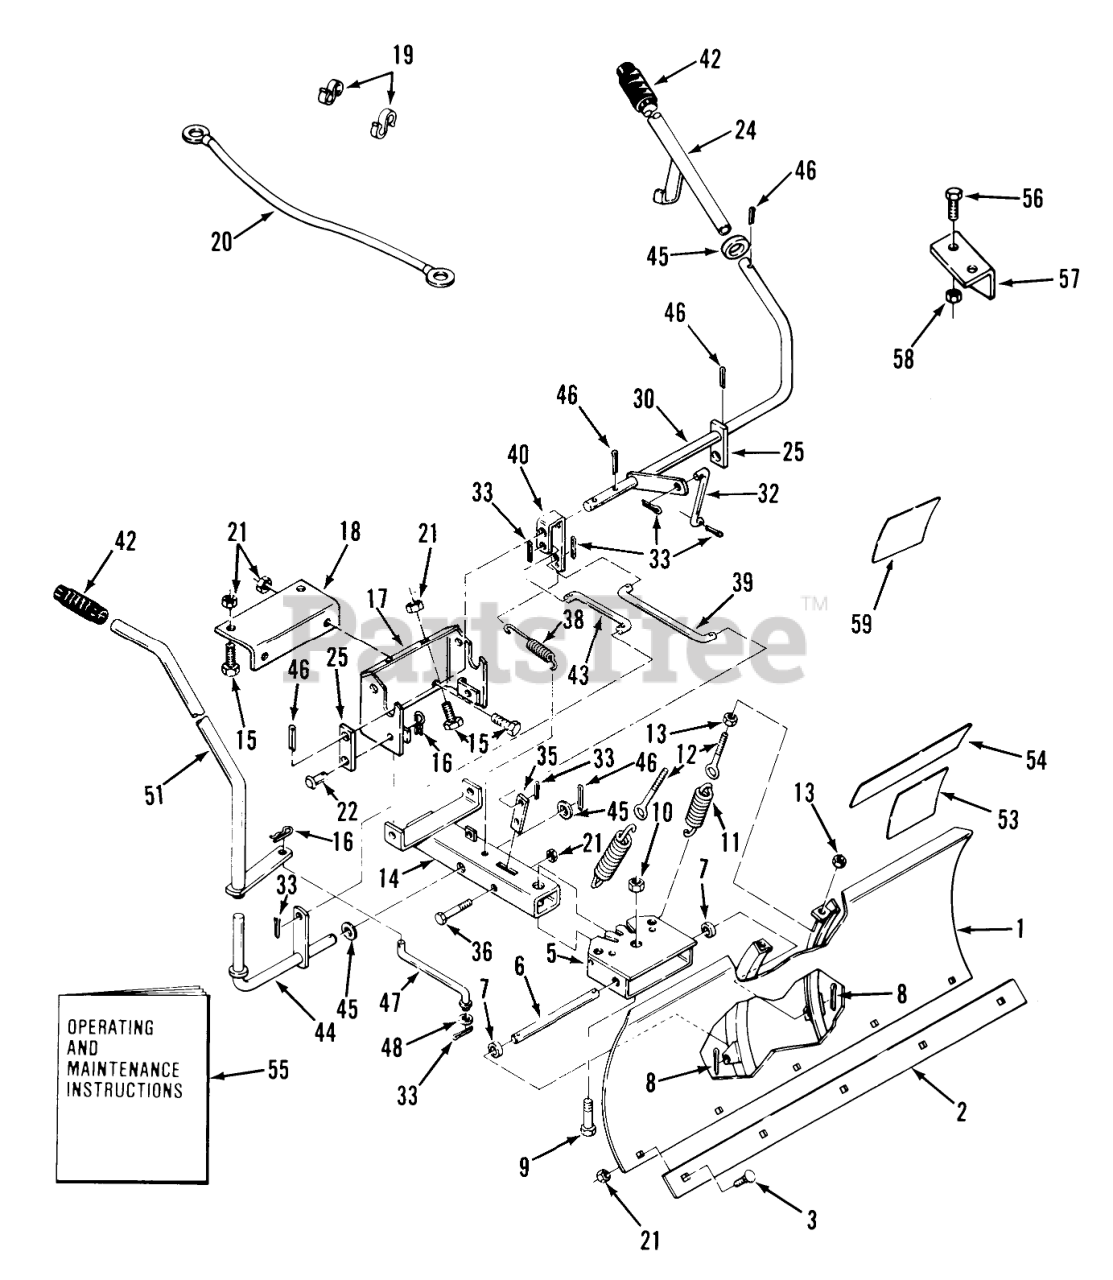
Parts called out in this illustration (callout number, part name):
1	Blade
2	Plate
3	Bolt-Carriage
5	ASSY-QUADRANT R
6	ROD-LOWER
7	Spacer
9	HEX HD CAP SCREW
10	Nut
11	SPRING
12	EYEBOLT
13	Nut
14	Frame
15	HHCS
16	Hairpin
17	ASS'Y-FRONT SUPPO R
18	Brace
19	SPEED CLIP
20	Wire 25" Long
21	NUT
22	CLEVIS PIN
24	Lift Tube
25	STRAP R
30	ASS'Y-LIFT CRANK R
32	Rod
33	Pop Rivet
35	LATCH-QUADRANT R
36	HHCS
38	SPRING
39	ROD-LATCH
40	BELLCRANK-LATCH R
42	HANDGRIP
43	ROD-BELLCRANK
44	Handle Pivot
45	Washer
46	Cotter Pin
47	ROD-ANGLING
48	Washer
51	ASSY-HANDLE R
53	DECAL-CAUTION
54	DECAL WHEEL HORSE
55	Operating and Maintenance Instructions
56	Bolt
57	BRACKET R
58	Nut
59	Decal-VIN Overlay
